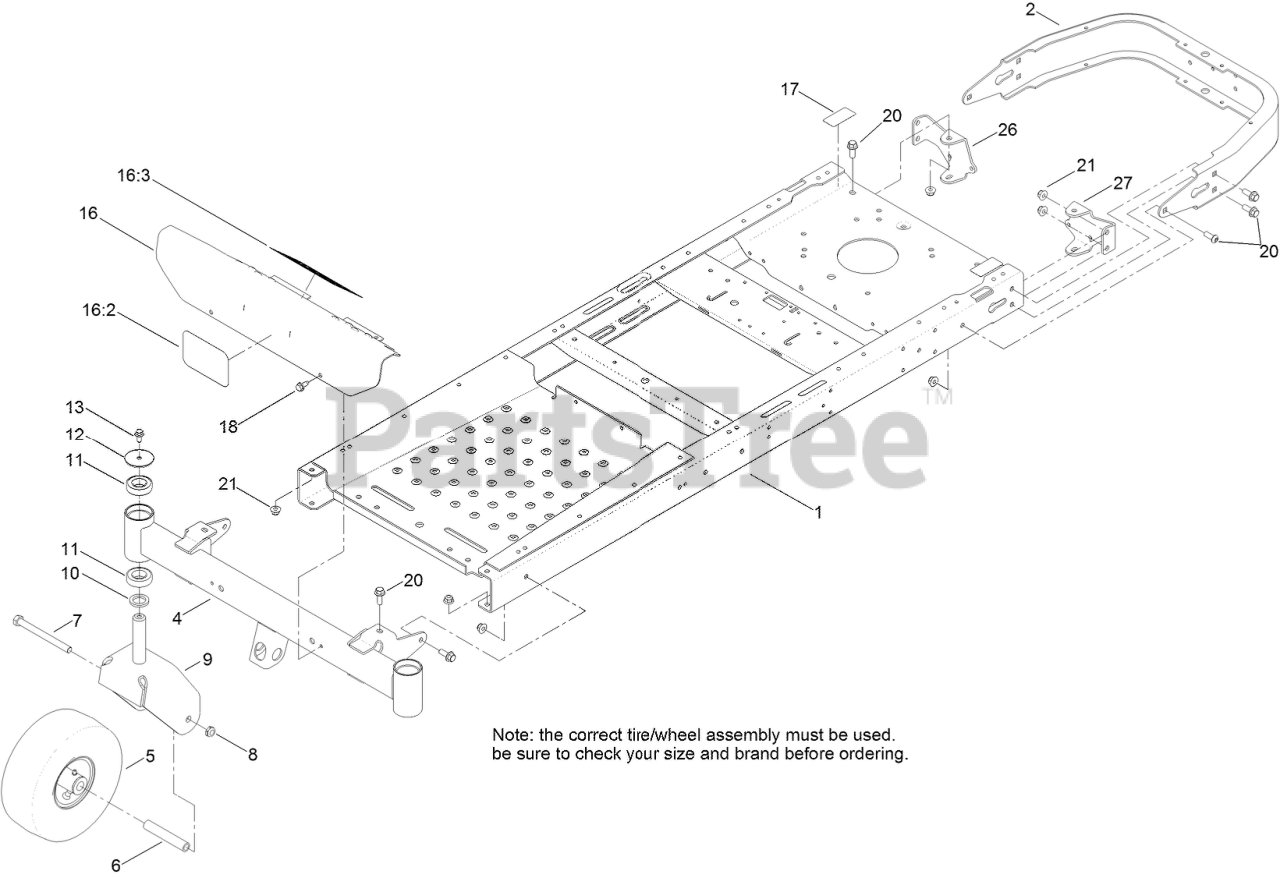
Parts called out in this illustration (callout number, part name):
2	BUMPER-REAR
4	AXLE-FRONT
5	CASTER WHEEL ASM (Cst)
5	CASTER WHEEL ASM (Kenda)
6	BUSHING-SPANNER
7	SCREW-HH
8	NUT-LOCK, NI
9	FORK-CASTER
10	WASHER-THRUST
11	BEARING-BALL
12	WASHER
13	SCREW-HHF
16	FOOTREST ASM
16:3	DECAL-DANGER
17	DECAL-BYPASS
18	SCREW-HWHTF
20	SCREW-HHF
20	SCREW-HSBH
21	NUT-HF, NI
26	MOUNT-HYDRO, REAR (RH)
27	MOUNT-HYDRO, REAR (LH)
